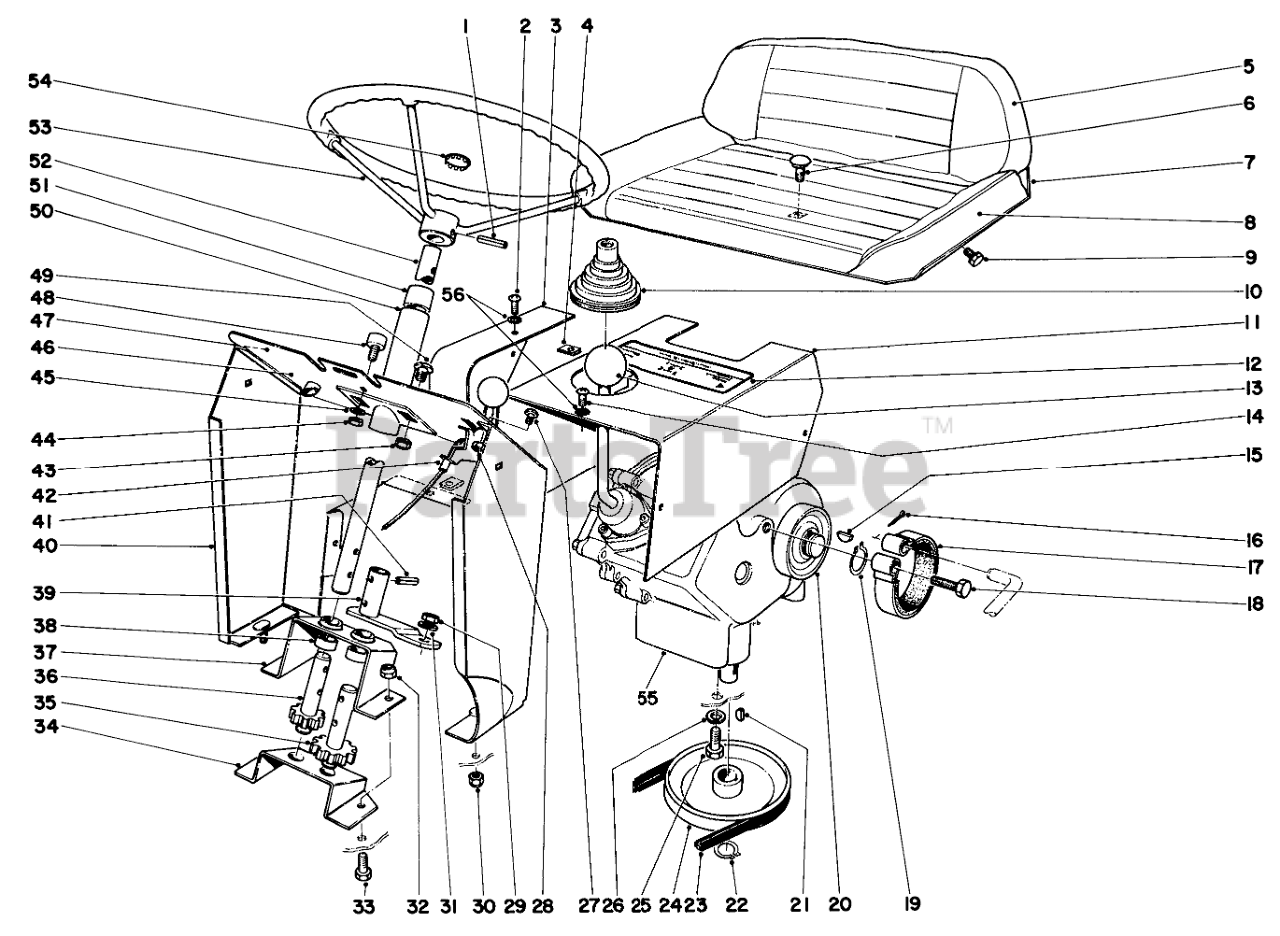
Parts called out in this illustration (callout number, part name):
1	PIN-ROLL
2	10-24 X 3/8 PAN HD SC
3	Chain Guard
4	NUT-CLIP,U
5	Seat Cover 905
6	SCREW-CARR
7	Frame Seat 905
8	Cushion Seat
9	Screw
10	Boot Shift Lever
11	Cover Transmission
12	Decal Shift Pattern
14	10-24 X 3/8 PAN HD SC
15	KEY-WOODRUFF
16	PIN-COTTER
17	Brake Band
18	He Ha. Screw
19	Ring-Snap
20	Brake Drum
21	KEY-WOODRUFF
22	RING-SNAP, EXTERNAL
23	TRANS TO ENGINE BELT
24	PULLEY
25	SCREW-HH
26	WASHER-LOCK/SP
27	Machine Screw
28	NUT-KEPS
29	NUT-HEX
31	WASHER-LOCK
32	Nut
33	SCREW-HH
34	Bracket Steering
35	Steering Gear
36	Pinion Gear
37	Support Steering
38	Spacer
39	Steering Arm
40	Rear Hood Support
41	PIN-ROLL, SLOTTED
42	Throttle Control
43	Nut
44	NUT-HEX
45	WASHER-LOCK
46	Rear Hood Support
47	Decal Control Panel 905
49	Truss Head Screw
50	Steering Tube Assy.
51	BUSHING
52	Shaft Steering
53	Steering Wheel
55	Transmission
56	WASHER-LOCK, EXT
